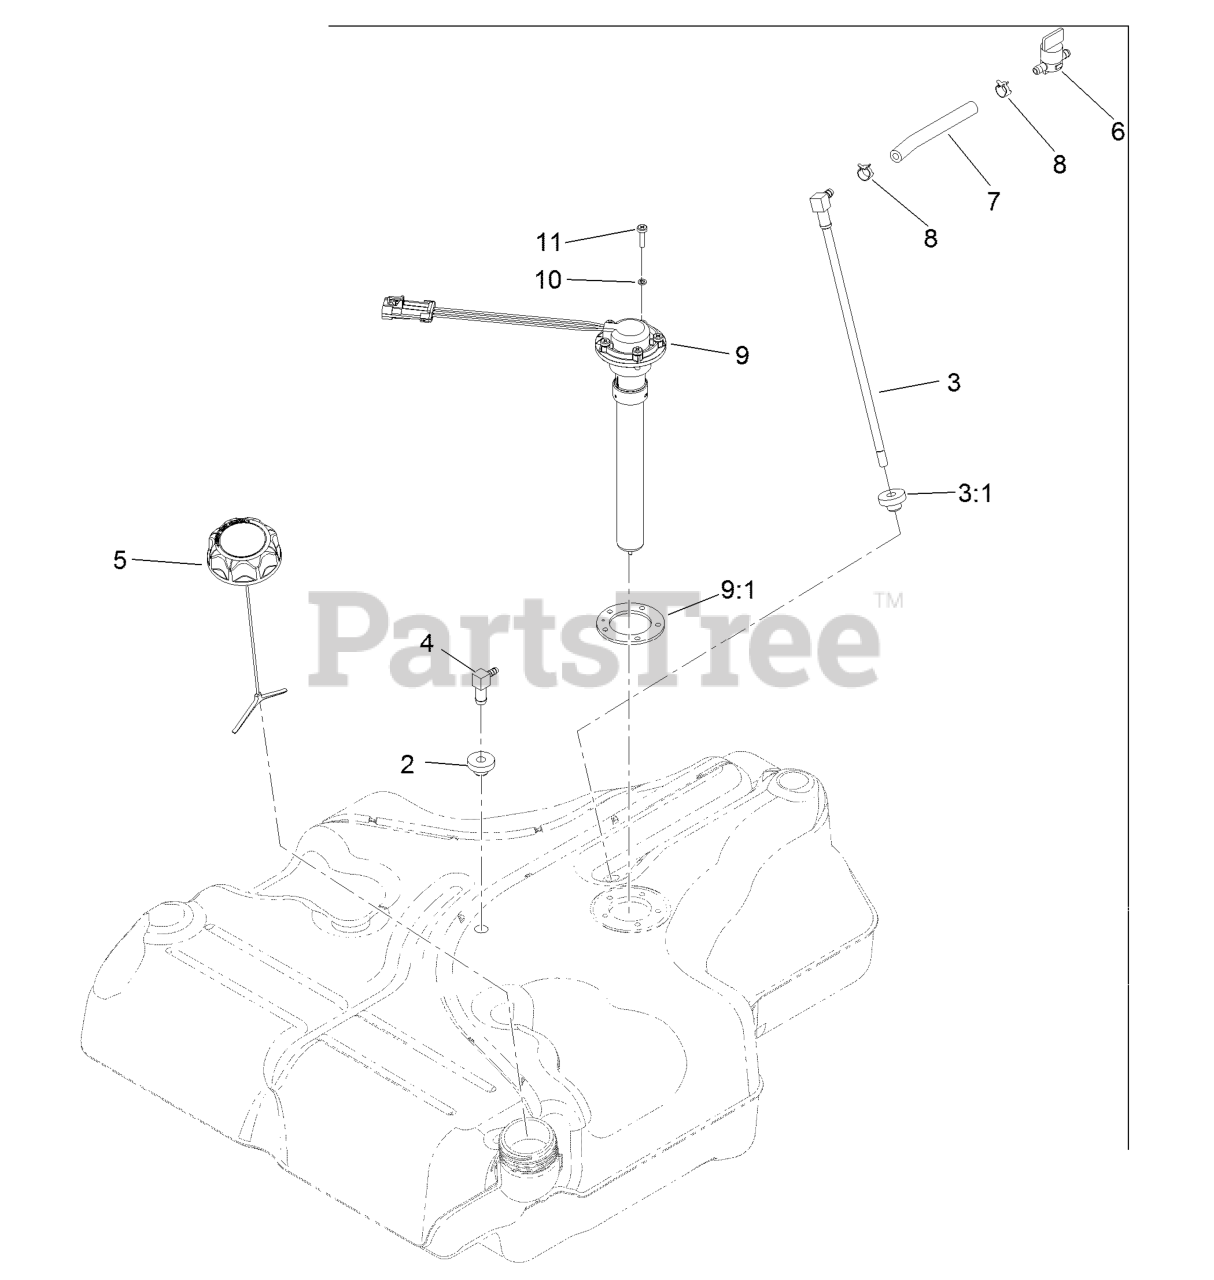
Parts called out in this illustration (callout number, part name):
2	BUSHING
3	FUEL LINE KIT (WITH GROMMET)
3:1	BUSHING
4	FITTING-90 ELBOW
6	VALVE-FUEL
7	HOSE-FUEL
8	CLAMP-HOSE
9:1	GASKET-SENDER, FUEL
10	WASHER-LOCK
11	SCREW-PAN
